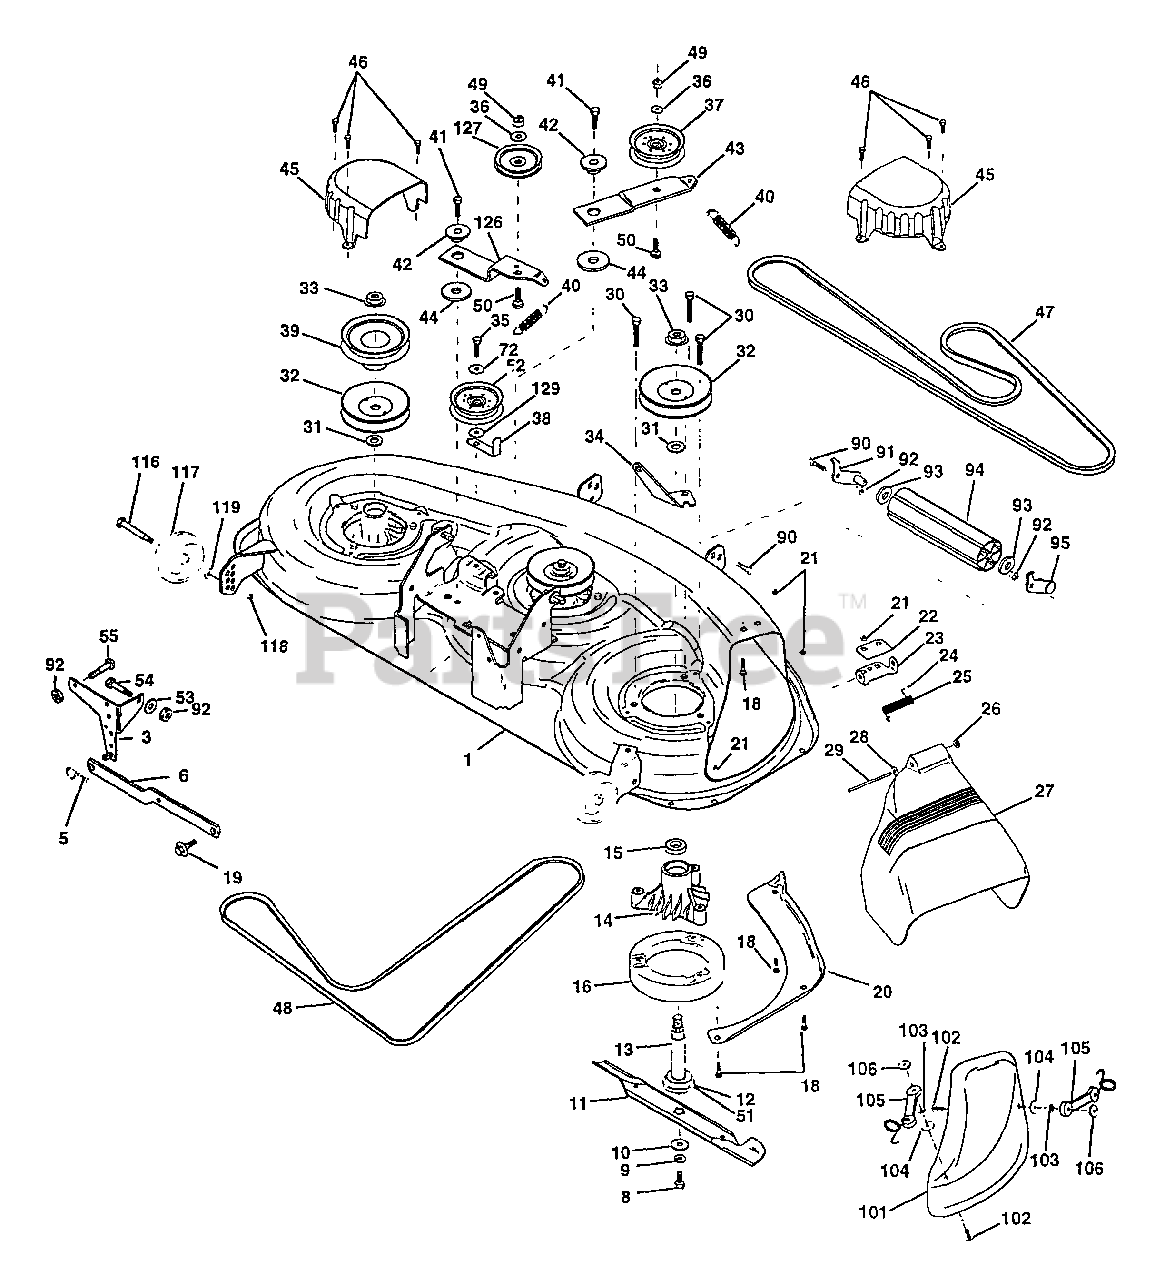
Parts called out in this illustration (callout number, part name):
1	Deck Asm., Mower 46"
3	Bracket Asm., Sway Bar
5	Retainer Spring
6	Arm, Suspension, Rear (Sway Bar)
8	Bolt, Patched 3/8-24 x 1-1/4 Gr. 8
9	Washer, Lock Hvy., Unplated 3/8
10	Washer, Hard Blade, Mower Vented
11	Blade, 46" Mower Deck
12	Bearing, Ball, Mandrel #6204
13	Shaft Asm. w/Lower Bearing
14	Housing, Mandrel
15	Bearing, Ball, Mandrel
16	Stripper, Mower Round
18	Bolt, Carriage 5/16-18 x 5/8
19	Bolt, Hex Head, Shoulder 5/16-18
20	Baffle, Vortex Mower 46"
21	Nut, Crownlock 5/16-18 UNC
22	Stiffener, Bracket
23	Bracket, Deflector
24	Cap, Sleeve
25	Spring, Torsion, Deflector
26	Nut, Push
27	Shield, Deflector Mower
28	Washer 11/32 x 5/8 x 16 Ga.
29	Rod, Hinge
30	Screw, Wsh Head, Thdroll
31	Washer, Spacer Mower Vented
32	Pulley, Mandrel
33	Nut, Flg. Top Lock Cntr. 9/16
34	Anchor, Spring Deck 46"
35	Screw, Thdroll 3/8-16 x 1-3/4 Tytt
36	Washer 13/32 x 13/16 x 16 Ga.
37	Pulley, Idler, Flat
38	Keeper, Belt, Idler
39	Pulley, Idler, Driven
40	Spring, Secondary 44/46/50 Vent
41	Screw, Thdroll 3/8-16 x 1-1/4 Tytt
42	Spacer, Retainer
43	Arm, Idler Secondary
44	Washer, Hardened
45	Cover, Mandrel Deck
46	Screw, Thdroll. 1/4-20 x 5/8
47	V-Belt, Mower, Secondary
48	V-Belt, Mower, Primary
49	Nut, Crownlock 3/8-16 UNC
50	Bolt, Carriage 3/8-16 x 1-1/2 Gr. 5
51	Washer, Felt
52	Pulley Idler 46 Pri. Drive
53	Washer 1 3/32 x 13/16 x 12 Ga.
54	Bolt Fin Hex 3/8-16unc x 1 Gr. 5
55	Bolt Rdhd Sqnk 3/8-16unc x 1
72	Washer 13/32 x 1 x 16 Ga.
90	Bolt, Fin, Hex 3/8-16 UNC x 1
91	Bracket, Asm Noseroller, LH
92	Nut, Lock, Hex w/Ins 3/8-16UNC
93	Washer 17/32 x 7/8 x 16 Ga.
94	Roller, Nose 38 & 42
95	Bracket, asm Noseroller RH
101	Cover, Mulching
102	Screw
103	Washer, Lock #10
104	Washer
105	Latch Asm, Bagger
106	Nut, Weld
116	Bolt, Shoulder
117	Gauge Wheel
118	Nut, Centerlock 3/8-16 UNC
119	Washer 3/8 x 7/8 x 14 Ga.
126	Arm, Idler, Primary Deck 46"
127	Pulley, Idler, V-Groove Dim. 4.25
129	Washer 13/32 x 3/8 x 3 Ga.
